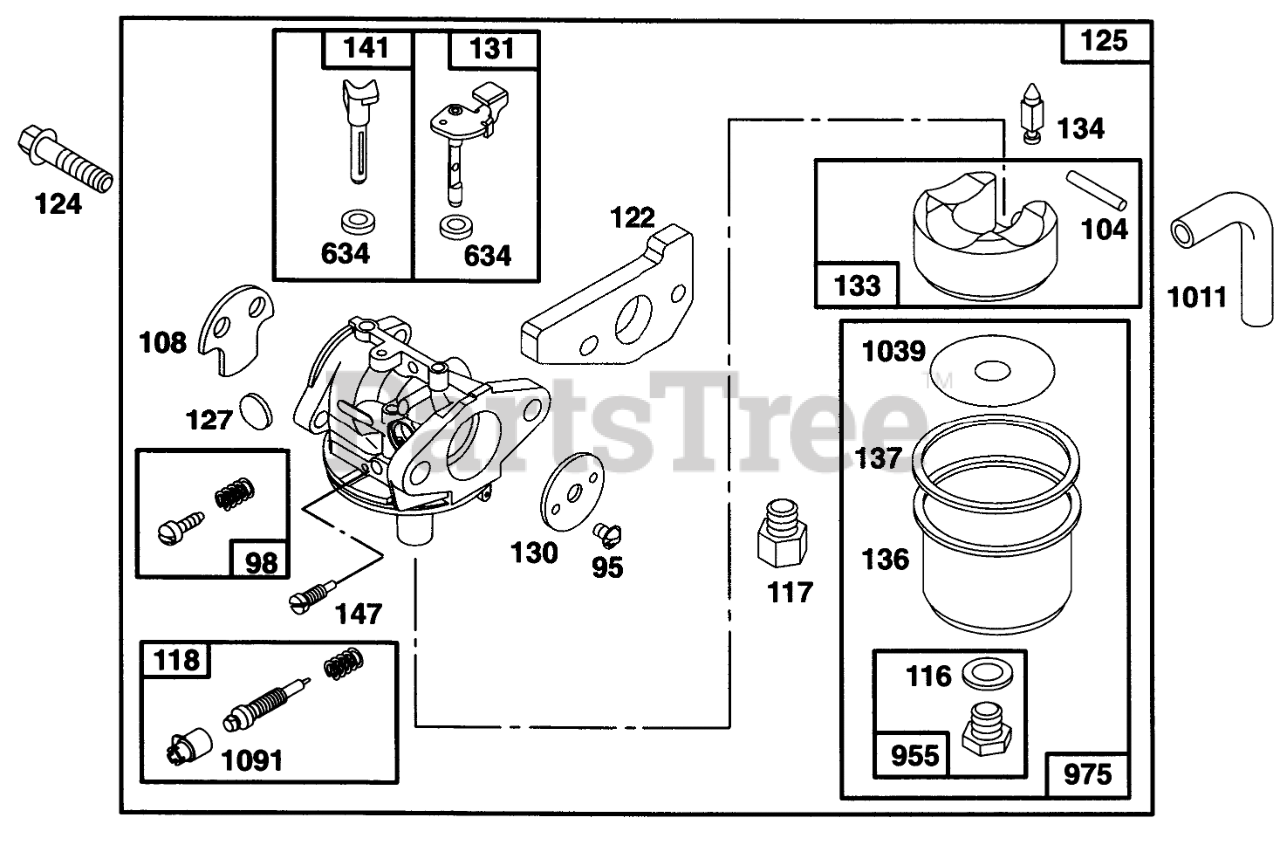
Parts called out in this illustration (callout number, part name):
95	SCREW - ROUND HEAD
98	IDLE ADJUSTING SCREW
104	FLOAT HINGE PIN
108	VALVE - CHOKE
116	SEALING GASKET
117	Jet-Main
118	VALVE/SPRING - NEEDLE
122	ADAPTER ASSEMBLY
124	HEX HEAD SCREW
125	ASSEMBLY - CARBURETOR
127	PLUG
130	THROTTLE VALVE
131	THROTTLE SHAFT
133	FLOAT-CARBURETOR
134	Valve-lnlet (Includes Seat)
136	FLOAT BOWL
137	FLOAT BOWL GASKET
141	CHOKE SHAFT
147	JET - PILOT
634	SEAL WASHER
955	HEX HEAD SCREW
975	CARBURETOR BOWL ASM
1011	VENT TUBE
1039	FLOAT LIMITER
1091	CAP - LIMITER
